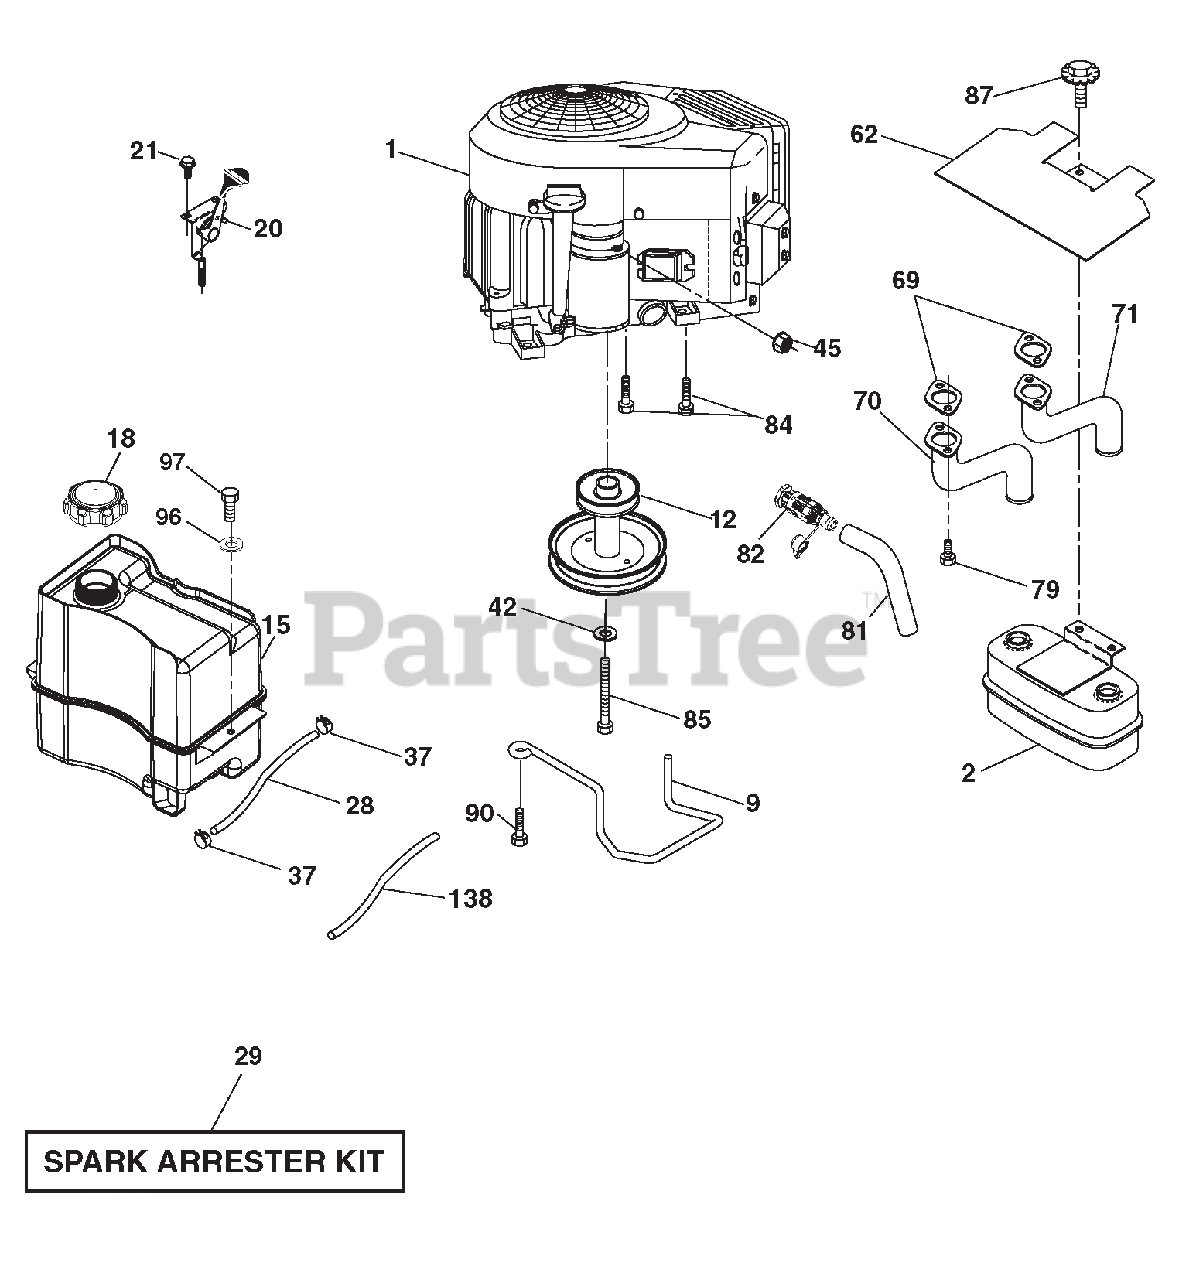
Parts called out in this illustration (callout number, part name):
1	ENGINE BRIGGS MODEL NO. 407777-3195-G5 (581081901)(ORDER PARTS FROM ENGINE MANUFACTURER.)
2	MUFFLER ASM.TWIN.LO-TONE
9	KEEPER.BELT.ENGINE.4.25"NSTG
12	ENGINE PULLEY
15	TANK.FUEL.2.5.GAL.
18	CAP FUEL
20	CONTROL THROTTLE/CHOKE
28	LINE.FUEL.20"
29	KIT.SPARK ARRESTOR(392390 B&S)
37	CLAMP.HOSE.BLK.
42	WASHER.LOCK.HVY HLCL.SPR.7/16
45	Nut, Keps Hex 1/4-20 unc
62	SHIELD.HEAT.MUFFLER.
69	GASKET MUFFLER
70	EXHAUST TUBE LH
71	EXHAUST TUBE RH
79	SCREW SOCKET HEAD 5/16-18 X 1
81	TUBE.DRAIN.OIL.EASY
82	VALVE OIL DRAIN
84	Screw 3/8-16 x <
85	BOLT.HEX.7/16-20X4XGR5-1.5THR.
87	BOLT.5/16-18UNCX3/4 W/SEMS.BLK
90	SCREW.3/8-16X1.SMGML.TAP/R.BLK
96	WASHER.9/32 X 7/8 X 16GA.
97	SCREW.HEXWSH.THDROL.1/4-20X3/4
138	PURGE.LINE.CARB
